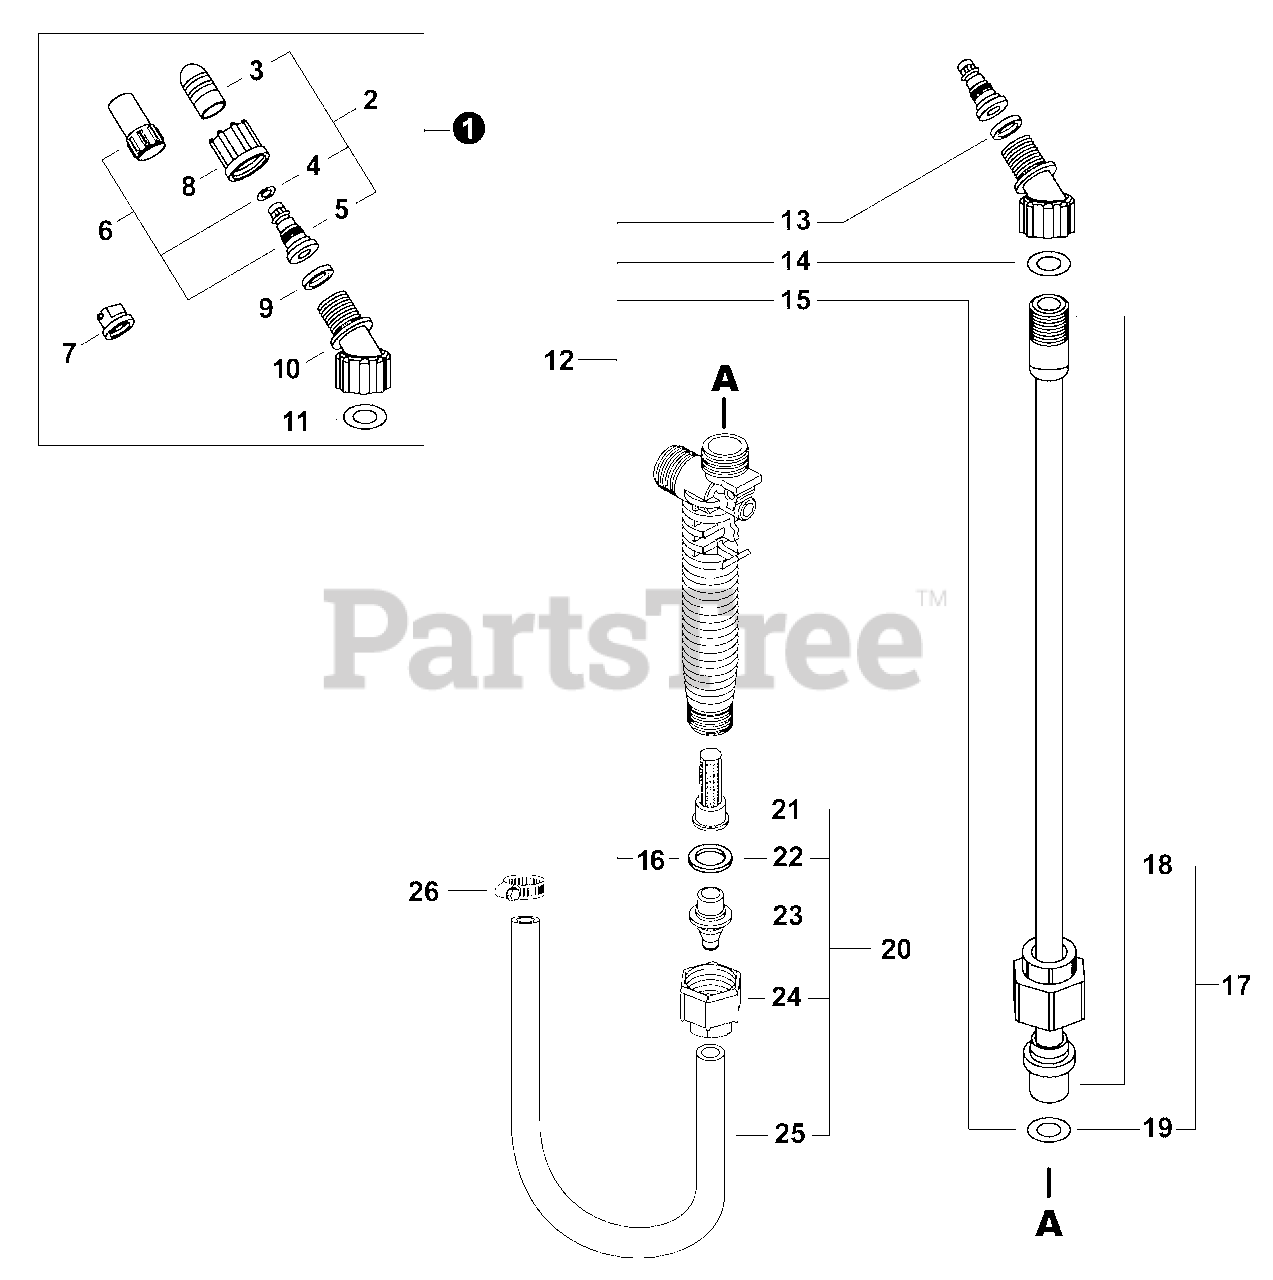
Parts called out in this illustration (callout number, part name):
1	NOZZLE KIT
2	NOZZLE KIT, BRASS
3	CAP, NOZZLE - BRASS
4	O-RING, NOZZLE
5	BODY, NOZZLE
6	NOZZLE KIT, PLASTIC
7	NOZZLE, FLAT FAN
8	NUT, NOZZLE
9	GASKET, NOZZLE
10	ELBOW, NOZZLE
11	O-RING, ELBOW
12	GASKET KIT, WAND
13	GASKET, NOZZLE
14	O-RING, ELBOW
16	GASKET, ADAPTER
17	WAND ASSY, METAL
18	WAND, METAL
20	HOSE KIT
21	FILTER, SPRAY GUN
22	GASKET, ADAPTER
23	ADAPTER, HOSE - BLACK
24	NUT, HOSE
26	CLAMP, HOSE
